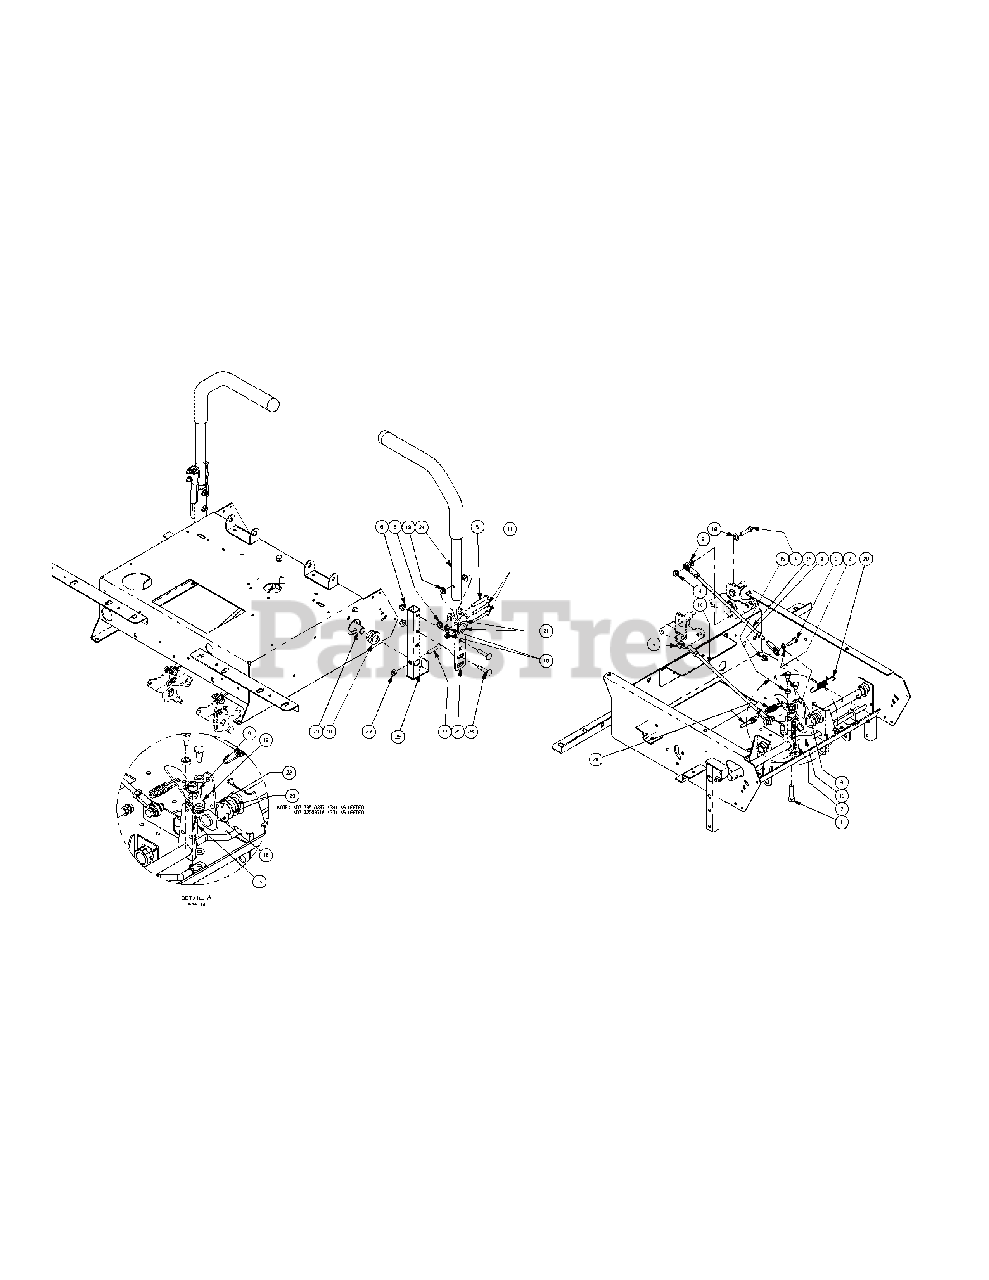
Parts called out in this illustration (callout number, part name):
1	Hex Cap Screw, 3/8-16 x 1-1/2
2	Flat Washer, 5/16
3	Hex Head Cap Screw, 5/16-18 x 1.00
4	HHCS, 5/16-18 x 1-1/4
5	Hex Cap Screw, 5/16-18 x 2.00
6	Nut, Flange Lock, 3/8-16
7	Flat Washer, 1.4 x .630 x .0515
8	Nut, 5/16-18, Lock
9	Shoulder Screw, 1/4-28
10	Nut, 1/4-20, Hex Flange Lock Nut
11	Hex Cap Screw, 1/4-20 x 2.00
12	Brake Lever Plate
13	Steering Input Shaft Assembly
14	Spacer, .385 ID x .625 OD x .869
15	Spacer, .380 x .563 x .196
16	Steering Link Rod
17	Socket Head Capscrew, 5/16-18 x 1.25
18	Bushing, .310 x .172 x .688 x .06
19	Control Lock Rod
20	Control Cable Lock Out
21	Spacer, .25 ID x .38 OD x 1.13
22	Retainer Ring, E-Clip
23	Lapbar Pivot Bracket
24	Lapbar Assembly includes:
25	Pivot Bracket Weldment
26	Carriage Bolt, 5/16-18 x 1.50
27	Nylock Nut, 5/16-18
28	Extension Spring, .544 OD x 3.35
29	Flat Washer, .793 ID x 1.24 OD x .060
30	Hex Flange Bearing, .752 ID
